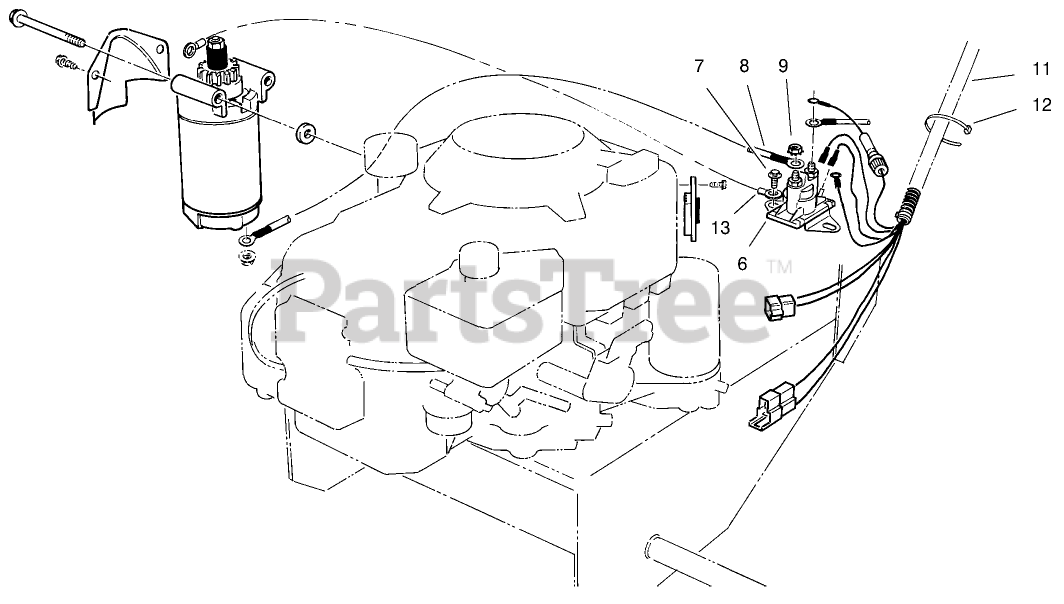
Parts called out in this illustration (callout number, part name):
6	SOLENOID
7	SCREW
8	WIRE-SOLENOID/STARTER
9	NUT-KEPS
11	HARNESS-WIRE
12	TIE-CABLE
13	WIRE ASM
